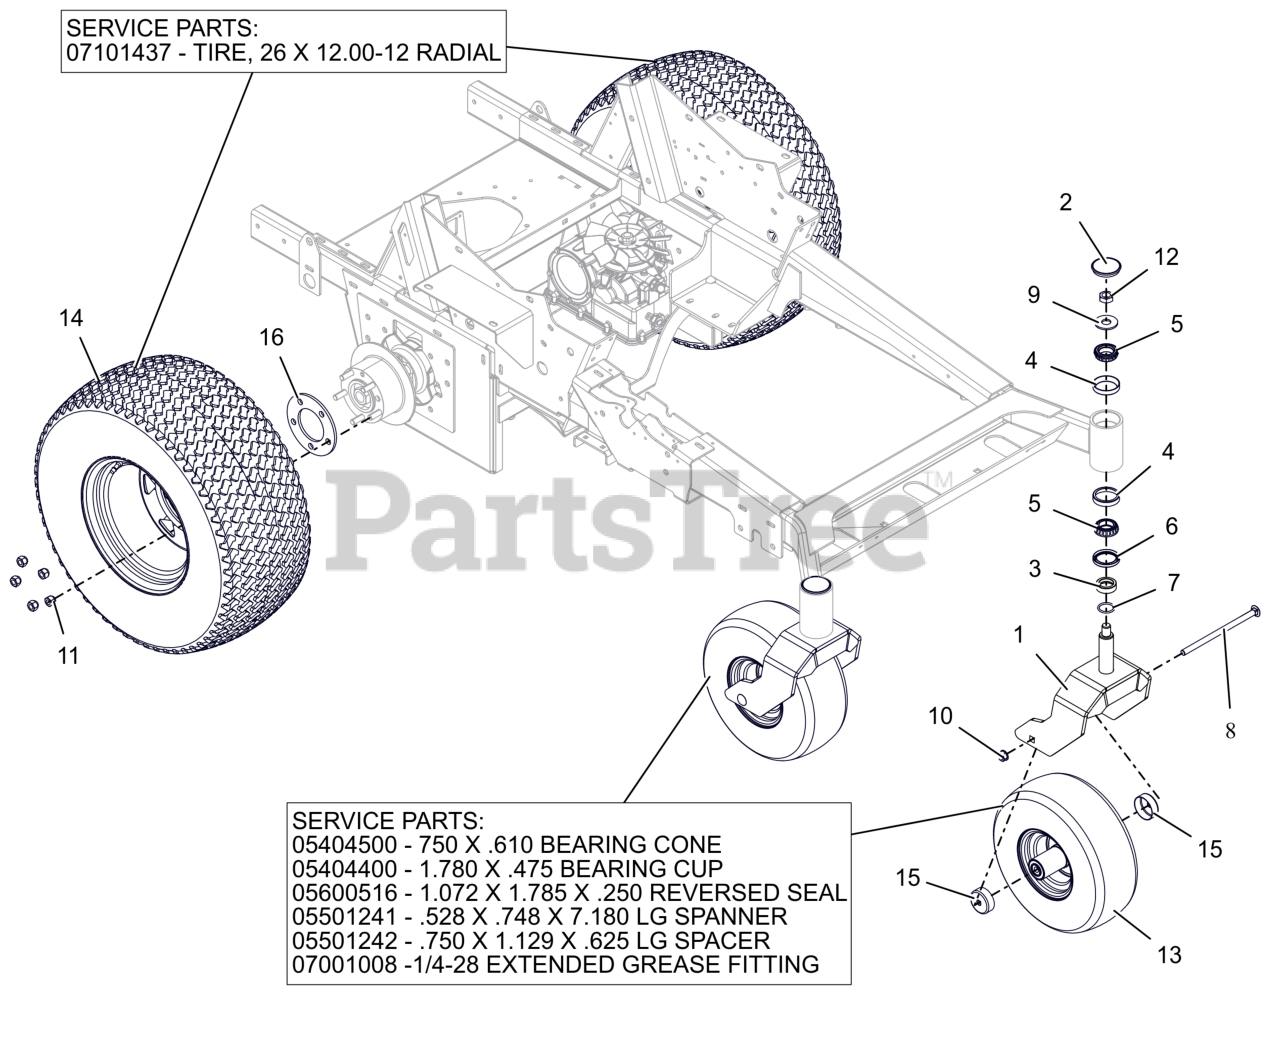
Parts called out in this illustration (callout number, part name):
1	WLDMT, CASTER FORK (RED)
2	CAP, DUST
3	SPCR, FRONT CASTER FORK
4	BRG-CUP 2.328X.465
5	BRG-CONE 1.25X.66
6	SEAL, OIL 1.75 X 2.332 X .312
8	BLT-RHSN .50-13X9.00 G5 ZCC NS
9	WSHR-FL-STL 0.812X2X0.148 ZCC
10	NUT-LK-CTR-FLG .500-13 GG ZCC
11	NUT, WHEEL .50-20 ZCC
12	NUT, JAM-TOPLOCK .750-16 ZCC
12	SPACER, .750X1.129X.625 LG
12	GREASE FITTING 1/4-28 EXTENDED
13	ASM, TIRE/WHEEL 15 X 6.00-6 SEMI
13	BRG-CONE .750X.61
13	BRG-CUP 1.781X.475
13	SEAL,1.072X1.785X.250 REVERSED
13	SPANNER, .528X.748X7.18 LG
14	ASM-WHL/TIRE26X12.00-12 RAD BK
14	TIRE- 26 X 12.00-12
15	SHIELD, WHEEL BEARING
16	SPCR, PT600 WHEEL (BLACK)
